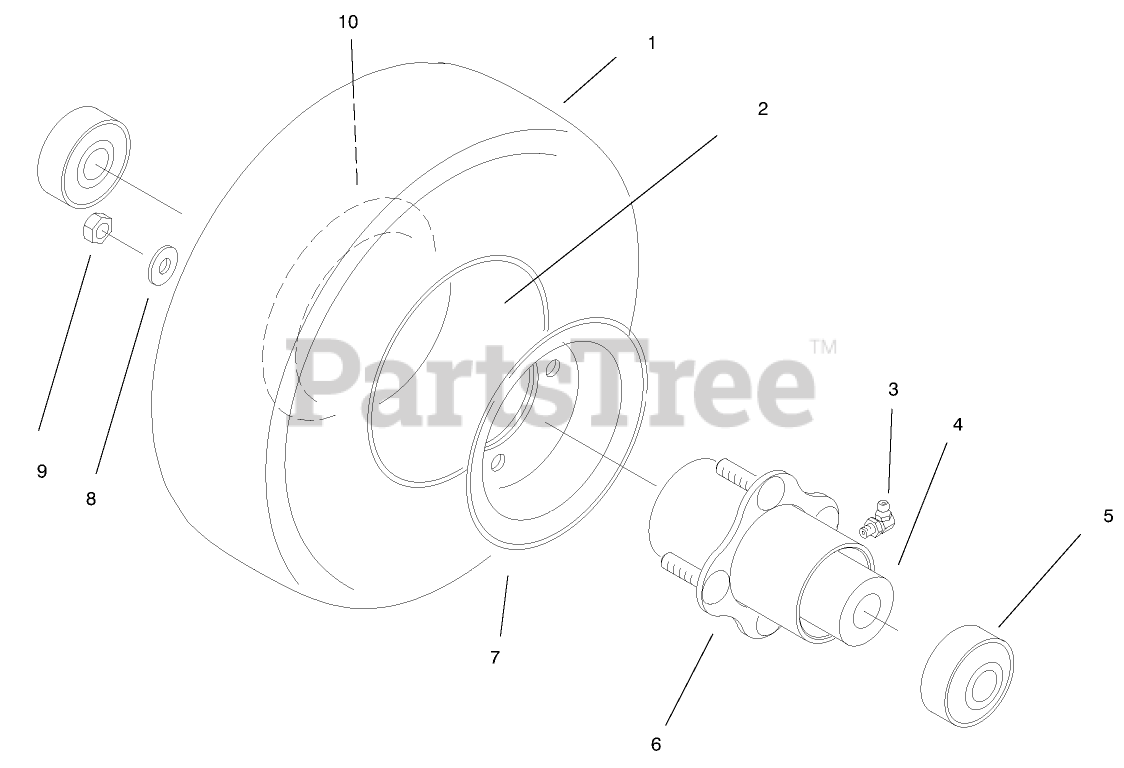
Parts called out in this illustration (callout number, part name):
2	TUBE-INNER (W/VALVE)
3	FITTING-GREASE
4	BEARING-ROLLER
5	BEARING-OUTSIDE
6	HUB-CENTER
7	MALE WHEEL HALF
8	WASHER-LOCK
9	NUT-HEX
10	FEMALE WHEEL HALF
